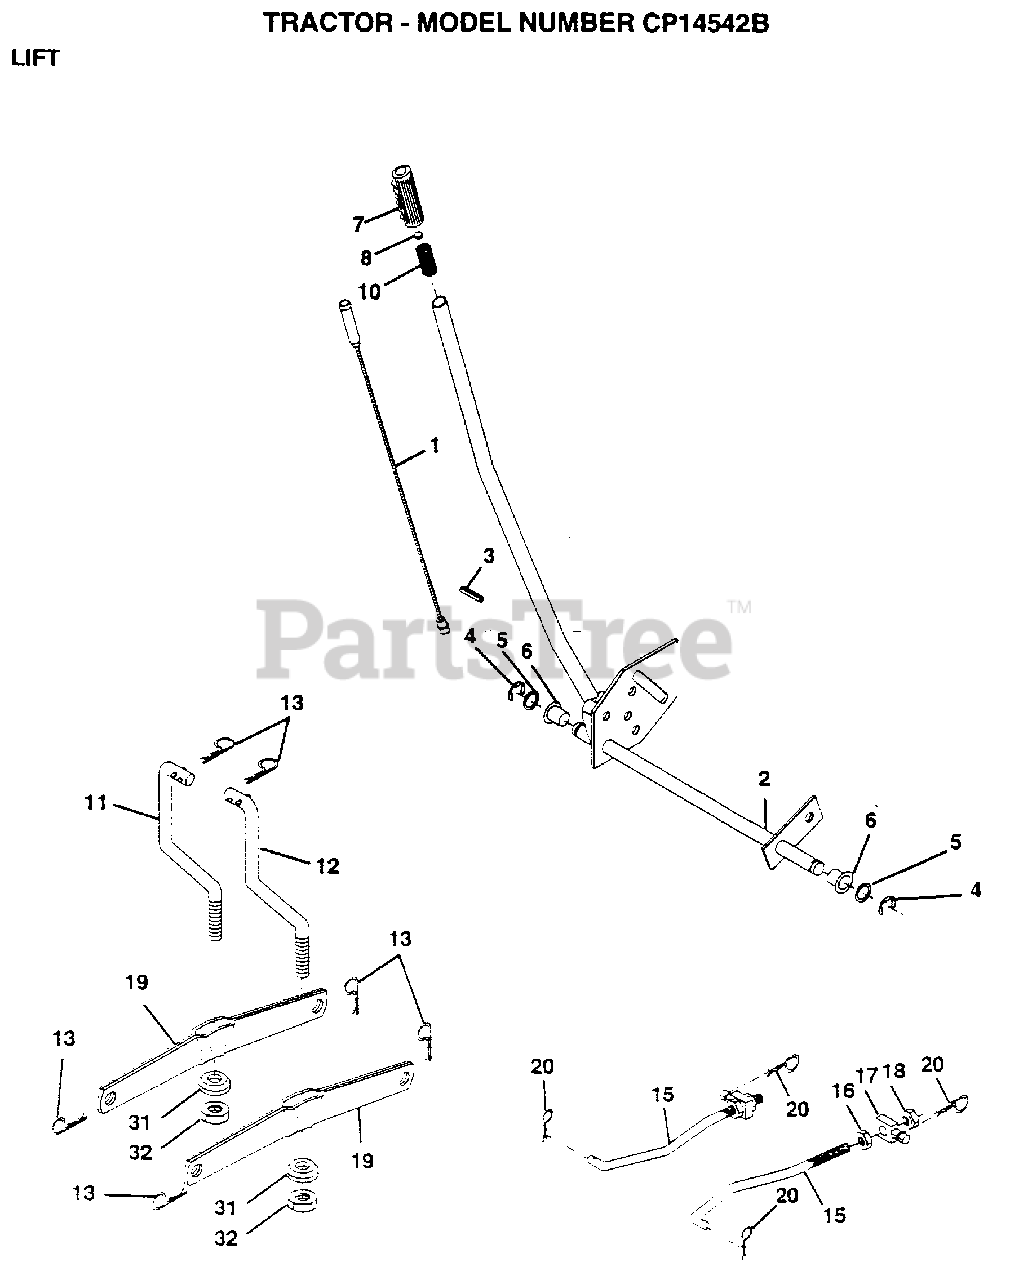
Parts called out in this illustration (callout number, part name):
1	WIRE ASM
2	HANDLE.LIFT.LH.
3	PIN GROOVE
5	WASHER
6	NYLON BEARING
7	GRIP
15	LINK.FRONT
16	NUT
17	TRUNION
18	NUT.LK.W/WSH.1/2.
19	ARM SUSP REAR
20	RETAINER.SPRING
31	BEARING PVT LH
32	NUT.CROWNLOCK.3/8
